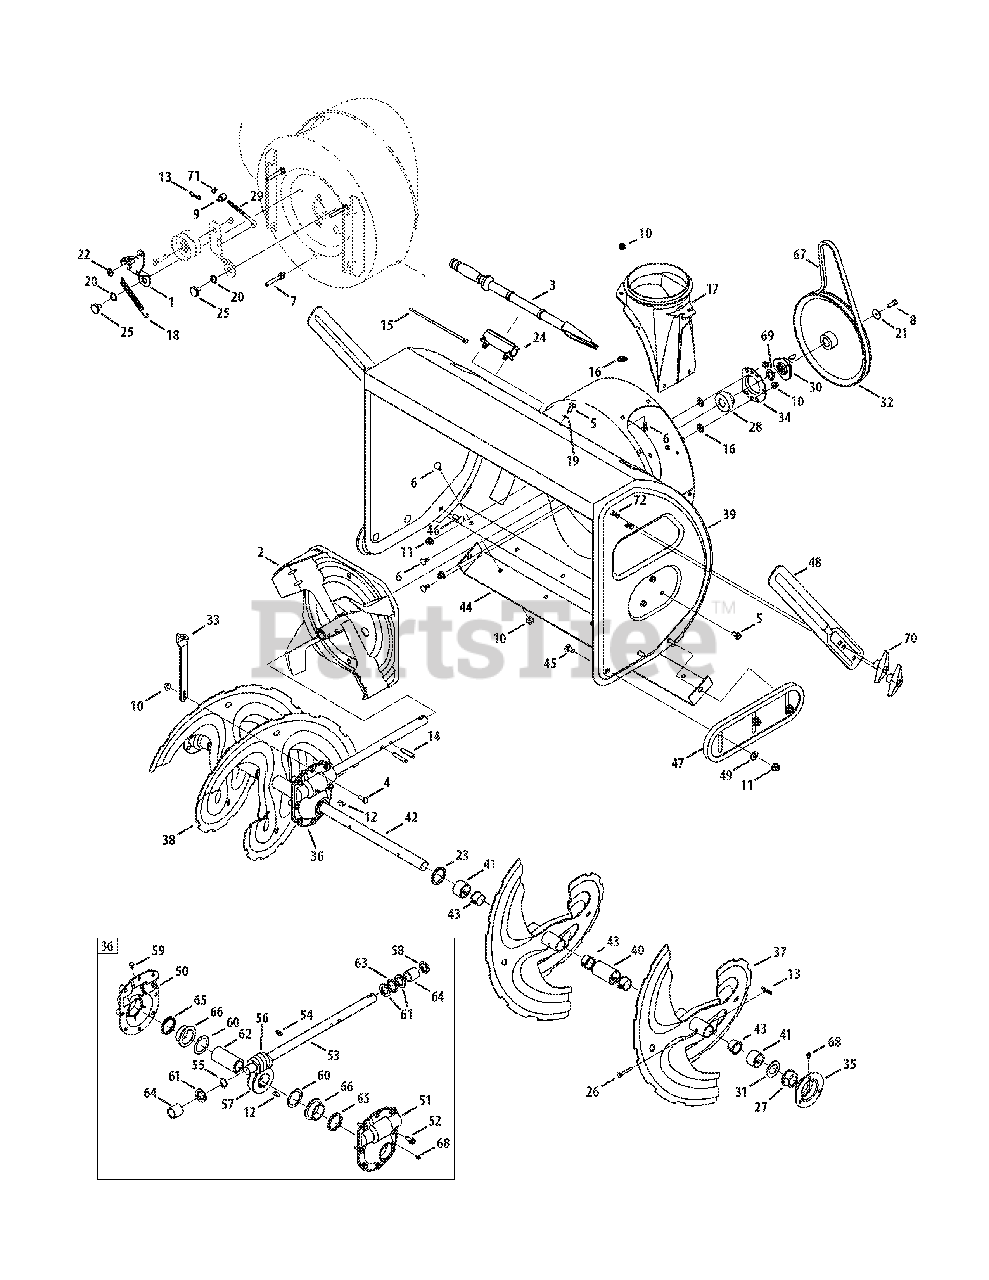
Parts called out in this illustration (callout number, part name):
1	Bracket Assy, Auger Brake
2	Impellar, 16"
3	Tool, Cleanout
4	Scr,Hex Cap, 5/16-18 x 1.00
5	Screw, 5/16-18 x .750
6	Screw, Carriage, 5/16-18 x .75
7	Screw, 5/16-18 x .4300
8	Screw, 5/16-24 x .875
9	Ferrule
10	Nut, Flnge Lk, 5/16-18
11	Nut, Flg Lk, 3/8-16
12	Key, Woodruff,1/4 x 3/4
13	Pin, Bowtie Cotter
14	Pin, Spirol, 5/16 x 1.75
15	Tie, Cable
16	Nut, Push
17	Adapter, Chute, 6"
18	Spring, Extension
19	Washer, .349 x .879 x .063
20	Washer, .625 x .885 x .015
21	Washer, Flat, .34 x 1.50 x .150
22	Washer, .344 x .75 x .12
23	Washer, 1.01 x 1.86 x .06
24	Clip, Mounting
25	Screw, Shoulder, .625 x .17
26	Pin, Shear, .25 x 1.75
27	Bearing, Flange w/Flats
28	Bearing, Self Aligning
29	Rod, Auger Idler
30	Pulley, Adapter, .75 Dia.
31	Spacer, 1.004 x 1.375 x .25
32	Pulley, Auger Drive, 10.0
33	Bracket, Gear Box Support
34	Housing, Bearing
35	Housing, Bearing
36	Gear Box Assembly, Auger
37	Spiral Assy, LH
38	Spiral Assy, RH
39	Housing, Auger - 33"
40	Spacer, 1.0 x 1.5 x 2
41	Spacer, 1.0 x 1.5 x 1
42	Axle, Spiral, 33"
43	Bushing, Flange, 1.051 x 1.16
44	Shave Plate
45	Bolt, Carriage, 3/8-16 x 1.0
46	Bolt, Carriage, 3/8-16 x 1.25
47	Shoe, Skid
48	Drift Cutter
49	Washer, Flat, .385 x .870
50	Hsg Assy Auger RH (Inc. 65 & 66)
51	Hsg Assy Auger LH (Inc. 65 & 66)
52	Screw, LD, 5/16-18 x .750
53	Shf, Drive, Auger
54	Key, Hi Pro, 3/16 x 3/4
55	Ext, Ret, Ring
56	Gear, Worm, Dbl Thread
57	Gear, Worm, LH
58	Seal, Oil
60	Washer, Flat, 1.52 ID x 2.0 OD
61	Washer, Flat, .88 ID x .38 OD
62	Shf, Gear, Worm
63	Brg, Thrust
64	Sleeve
65	Oil Seal
66	Flange Bearing
67	V Belt,4L x 44.60 Lg.
68	Lube Fitting, 3/16 #70
69	Washer, Flat, .78 x 1.49 x .08
70	Wing Knob
71	Jam Nut, 5/16-18
72	Screw, Carriage, 5/16-18 x 1.0
